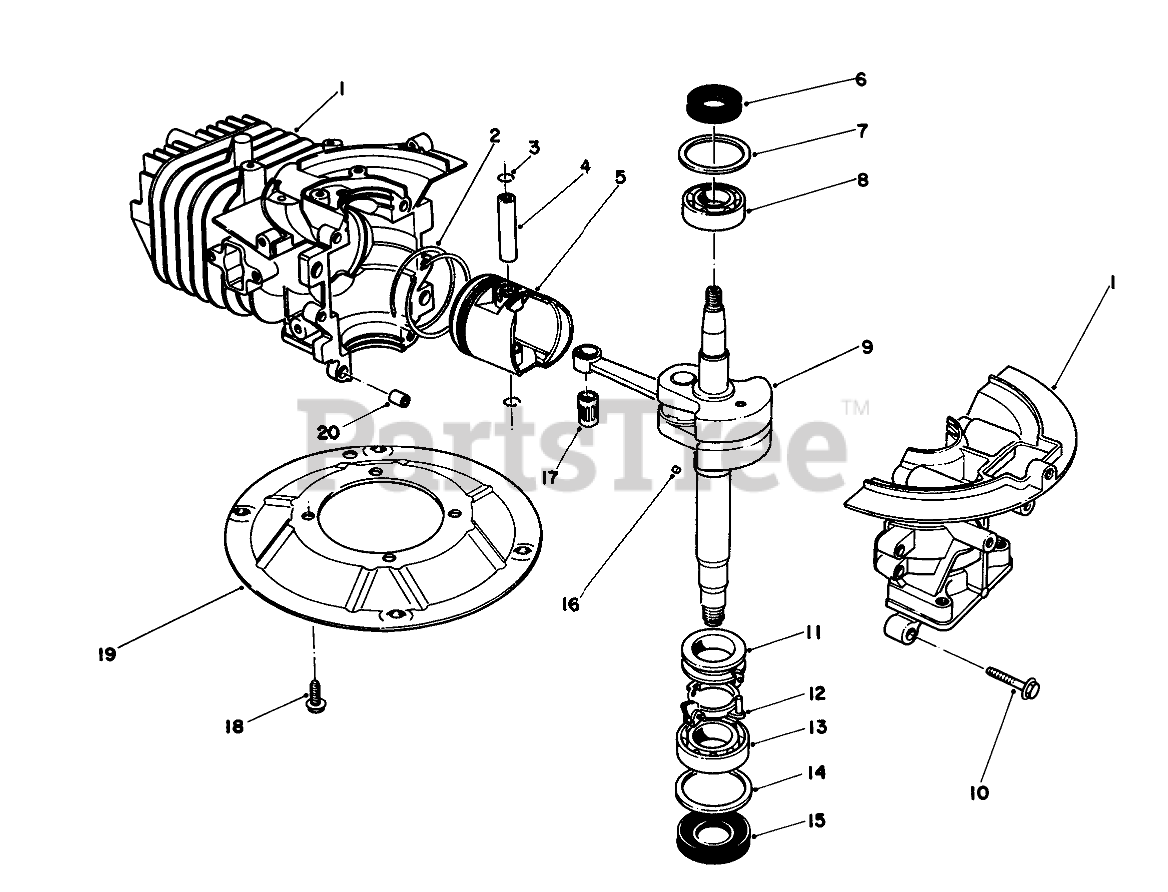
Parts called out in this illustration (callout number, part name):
1	CRANKCASE
2	RING SET
4	PIN-PISTON
5	Piston
6	OIL SEAL
7	WASHER-UPPER
8	BEARING-UPPER
9	CRANKSHAFT
11	SPACER
12	BRACKET
13	LOWER BRG
14	WASHER-LOWER
15	SEAL-OIL
17	BEARING
19	PLATE-MOUNTING
